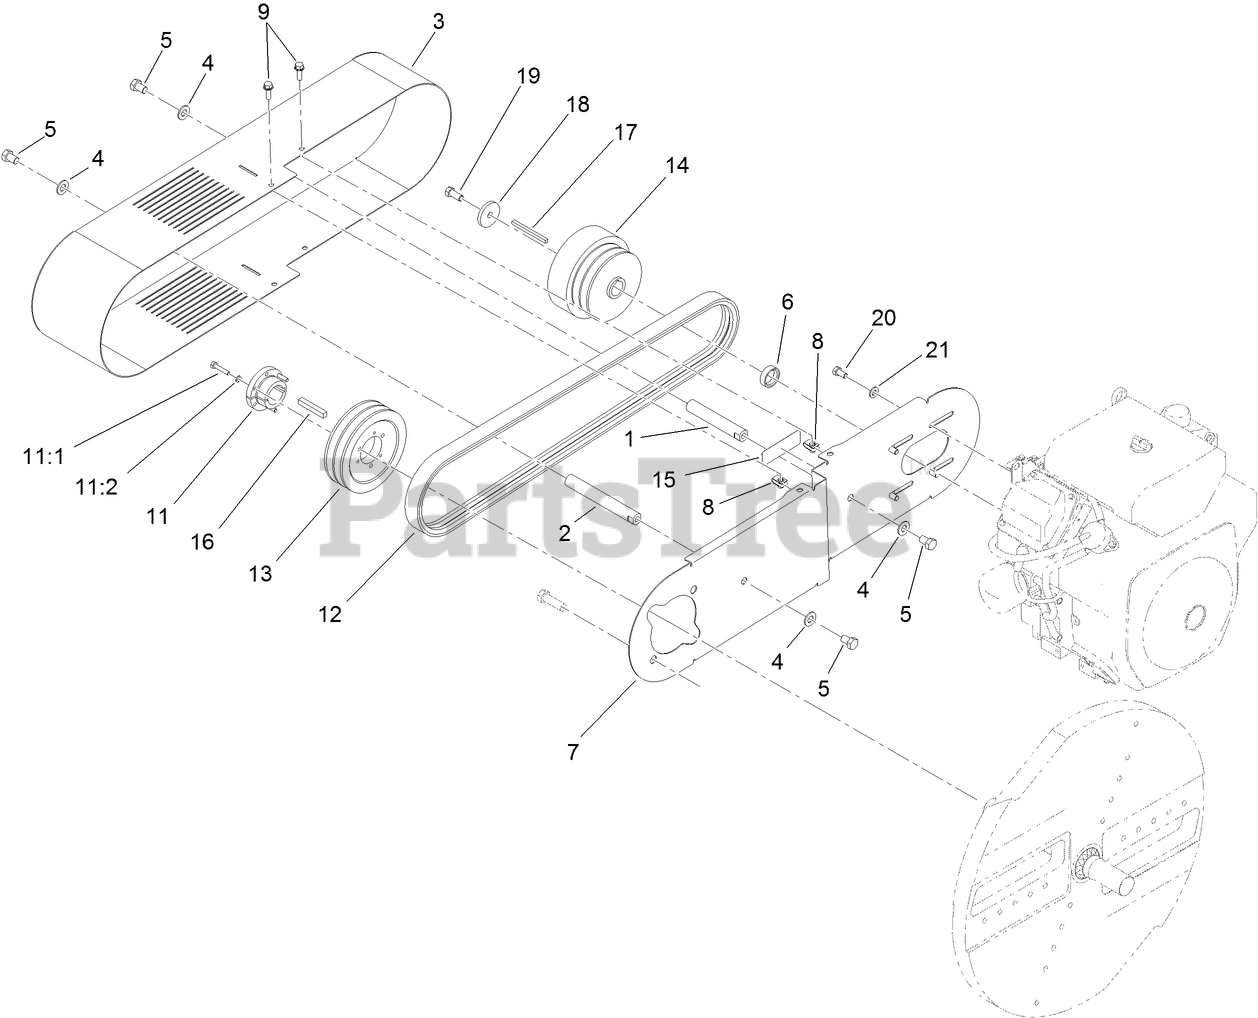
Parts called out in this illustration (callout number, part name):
1	TUBE-STANDOFF, SHORT
2	TUBE-STANDOFF, LONG
3	BELT COVER ASM
4	WASHER-FLAT
5	SCREW-HH
6	SPACER
7	GUARD-BELT, INNER
8	NUT-CLIP, U
9	SCREW-HHF
11	BUSHING-PULLEY
11:1	SCREW-HH
11:2	WASHER-LOCK
12	BELT-V, BANDED
13	PULLEY
14	CLUTCH-CHIPPER
15	DECAL-WARNING, SHIELDS
16	KEY-SQUARE
17	KEY-SQUARE
18	WASHER-CLUTCH
19	SCREW-HH
20	SCREW-HH
21	WASHER-FLAT
